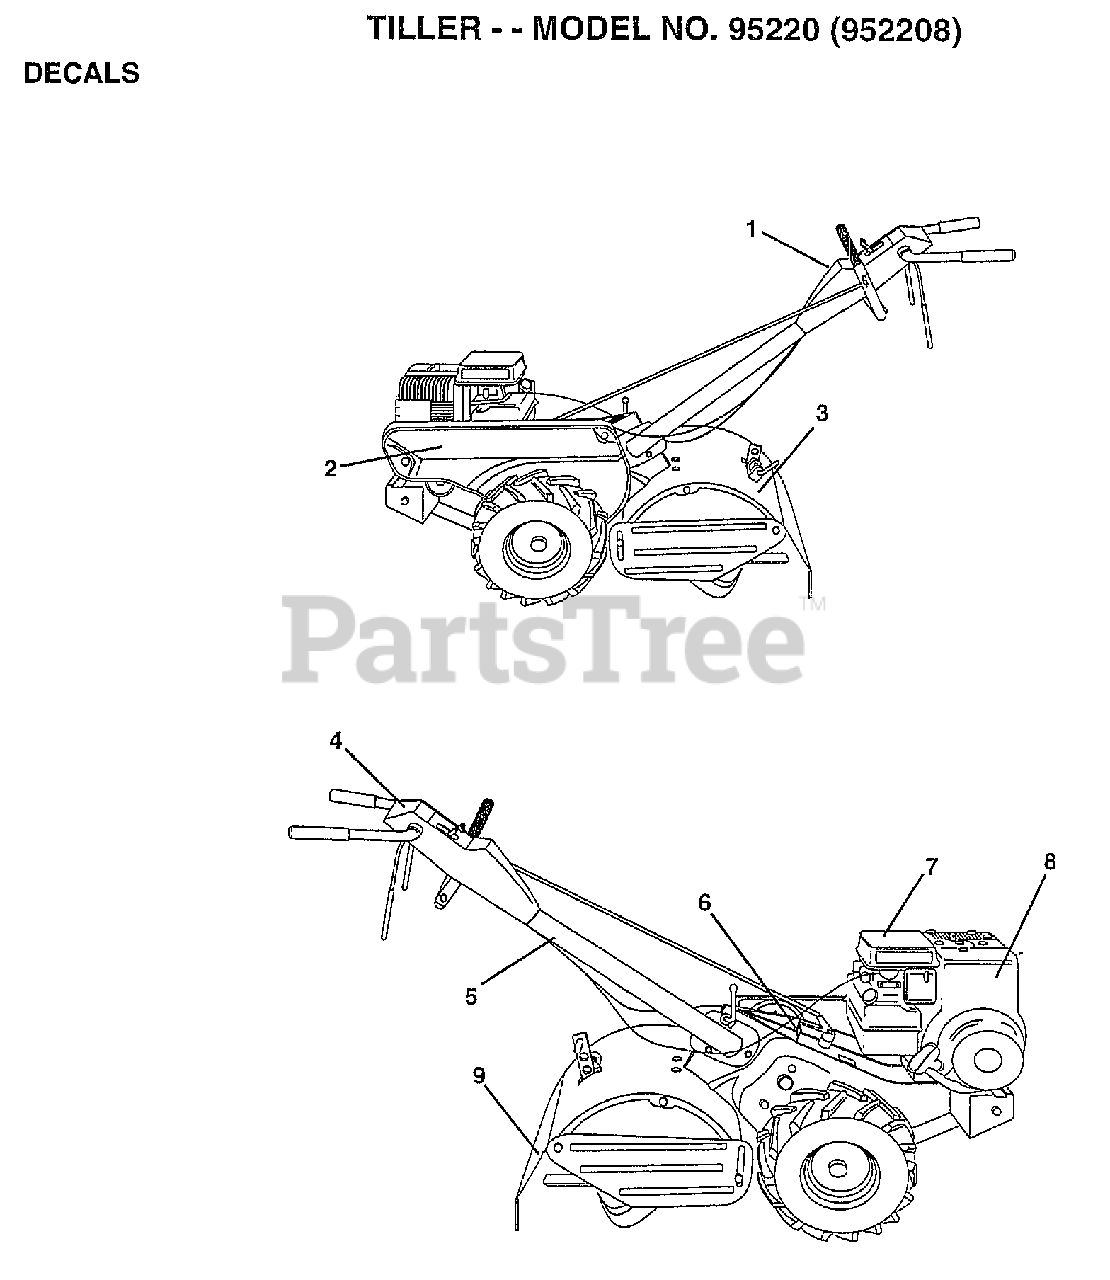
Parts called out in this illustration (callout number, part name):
1	DECAL.PNL.CONTROL
2	DECAL.LOGO.
4	DECAL.INSTRUCTION
5	DECAL TI
6	DECAL CRT
8	DECAL, BRIGGS & STRATTON
9	DECAL TI
